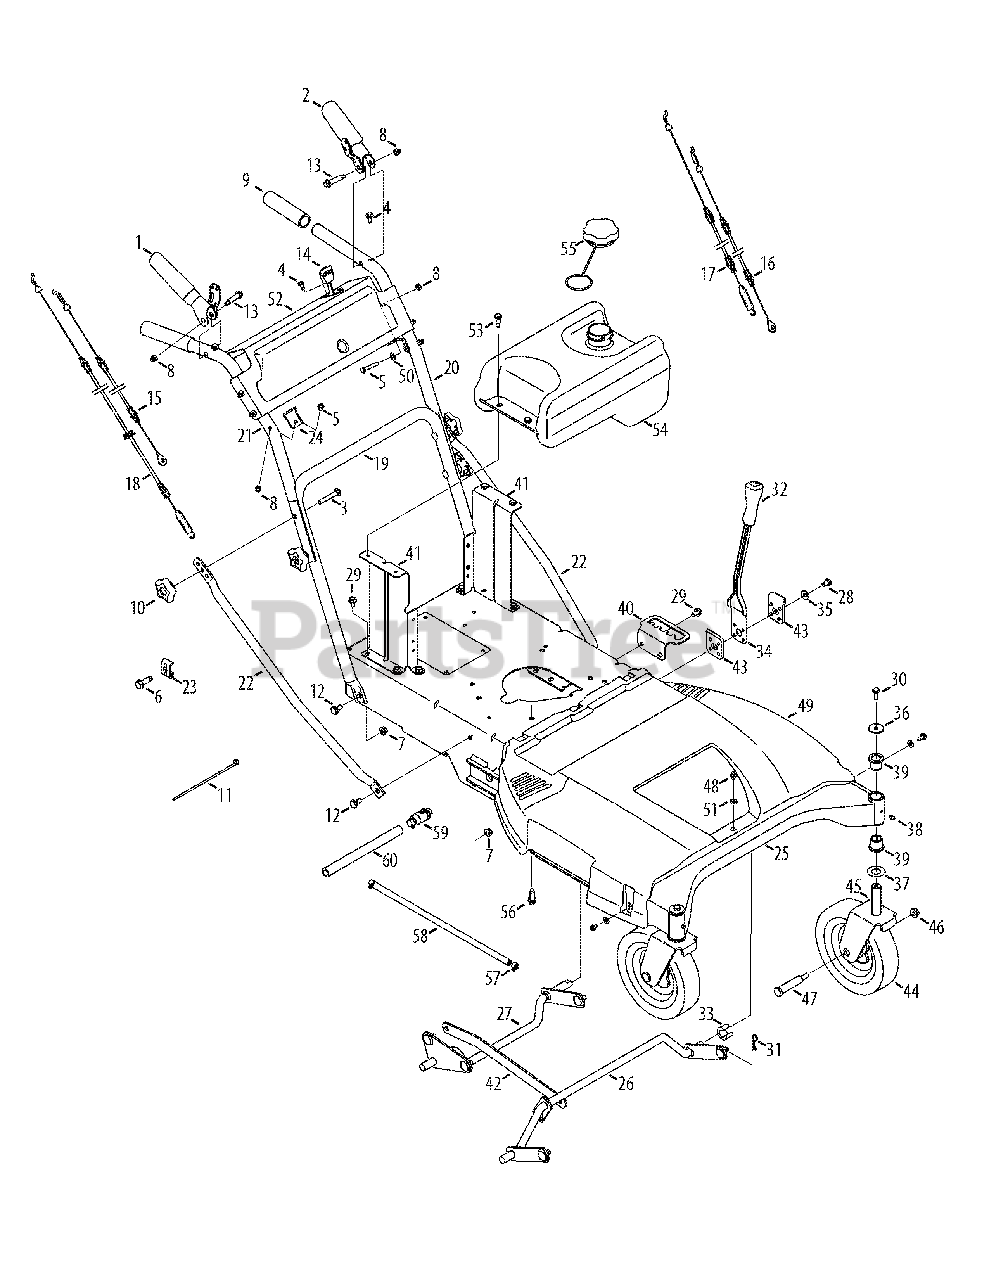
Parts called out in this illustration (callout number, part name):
1	RH Lever Assembly Bracket
2	LH Lever Assembly Bracket
3	Screw, Carriage, 5/16-18 x 2.25
4	Screw, 1/4-20 x 0.500
5	Hex Screw, 1/4-20 x 1.50
6	Screw, #10-32 x 0.625
7	Nut, Flangelock, 5/16-18
8	Lock Nut Cap, 1/4-20
9	Grip, 1.0 ID x 5.0 LG
10	Star Knob, 5/16-18
11	Cable Tie, 3/16 x .05 x 7.4
12	Screw, Shoulder, .435 x .178-5/16 x .56
13	Screw, Shoulder, .375 x 1.355 x 1/4-20
14	Throttle/Choke Cable, 38.0 x 1.1 EXT
15	RH Brake Cable
16	LH Brake Cable
17	Wheel Clutch Cable
18	Deck Clutch Cable
20	Upper LH Handle
21	Upper RH Handle
22	Adjustable Handle Brace
23	Casing Clamp
24	RH Cable Mount Bracket
24	LH Cable Mount Bracket
25	Frame Assembly
26	Front Deck Lift Assembly
27	Rear Deck Lift Assembly
28	Hex Screw, 5/16-18 x .50
29	Screw, 5/16-18 x 0.625
30	Hex Screw, 5/16-24 x .750
31	Click Pin, .092 x 1.64 LG
32	Grip Handle, 1/2
33	Plastic Spacer, .63 ID x .75 LG
34	Deck Height Lever
35	Washer, Bell, .340 x .872 x .060
36	Washer, Flat, .330 x 1.25 x .120
37	Washer, Flat, .760 ID x 1.50 OD
38	Drive Lube Fitting, 3/16
39	Flange Bearing, .760 x .941 x 1.0
40	Height Adjustment Bracket
41	Fuel Tank Mount Bracket
42	Link Pivot Bracket
43	Lever Pivot Bracket
44	Caster, Wheel, 8 x 1.75
44	Bearing, Flange w/ftg
45	Wheel Caster Bracket
46	Nut, Flangelock, 3/8-16
47	Bolt, Shoulder, .625 x 2.515 x 3/8-16
48	Screw, 1/4-14 x 0.625
49	Belt Cover
50	Washer, Bell, .265 x .75 x .062
51	Washer, Flat, .25 x .630 x .0515
53	Screw, Shoulder, .3175 x .188, 1/4-20
56	Screw, 3/8-16 x 1.250
57	Hose Clamp, .490 DIA.
58	Fuel Hose, Low Permeation, 1/4
60	Extension Hose
